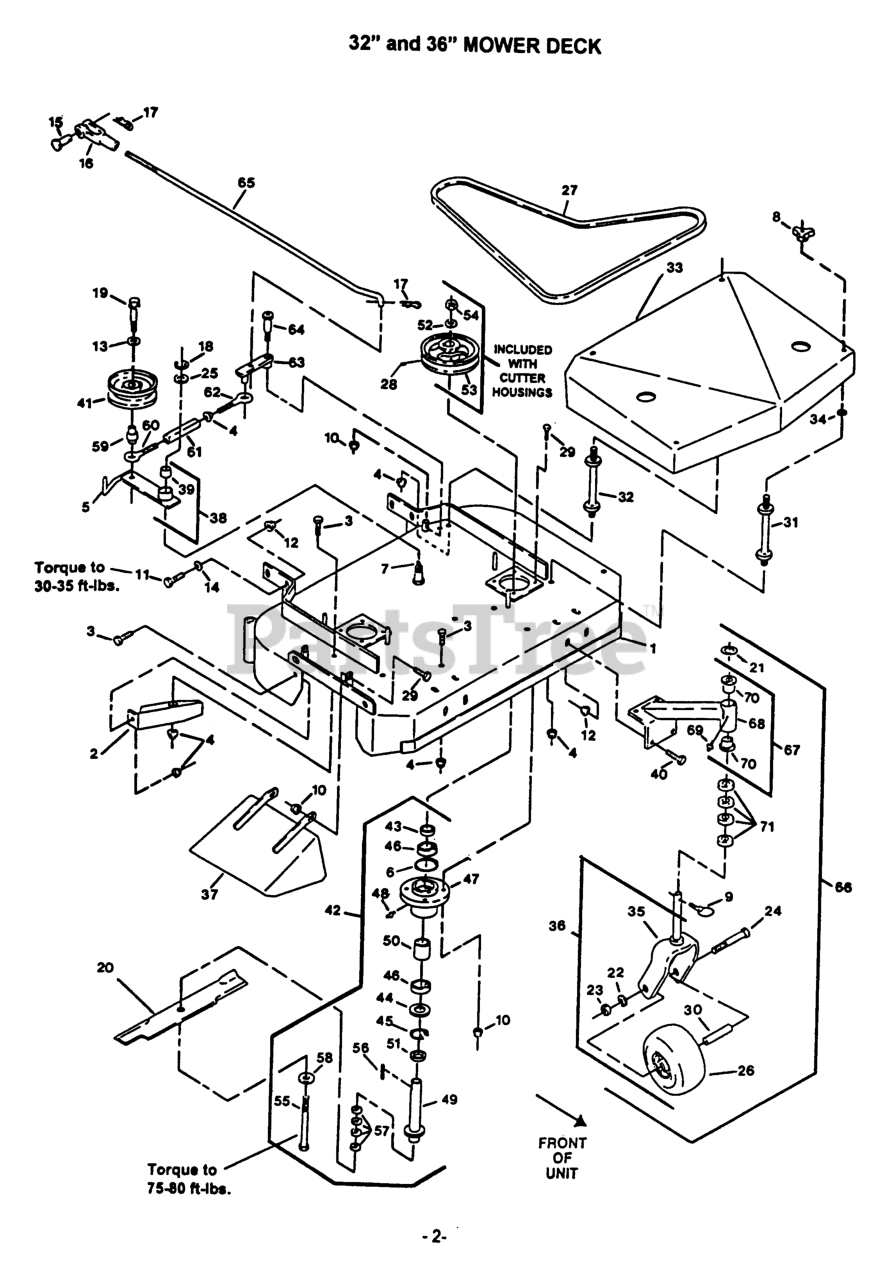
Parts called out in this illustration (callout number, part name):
2	BAFFLE-DOGLEG
8	KNOB-3 PRONG
15	PIN-CLEVIS
16	YOKE-ADJUSTABLE
17	PIN-COTTER
21	WASHER-FLAT
25	WASHER-SPINDLE
27	BELT,BLADE DRIVE
28	SCREW-SET
31	STUD-SHIELD, BELT (SHORT)
32	STUD-SHIELD, BELT (LONG)
37	Chute
39	BEARING,POWDERED METAL
42	ASM,HOUSING CUTTER
44	SEAL,DUST
45	RING,SNAP WLDS N5000-244
46	BEARING,HD SPINDLE
47	HOUSING,CUTTER
50	SPACER,BRG/BRG
51	SPACER,BEARING &SPINDLE
52	WASHER-RETAINER, SHEAVE
55	SCREW-CAP, HH
58	WASHER-SPRING
59	BUSHING-ENGAGEMENT
60	EYEBOLT-THREAD, LH
61	BODY-TURNBUCKLE
62	EYEBOLT-THREAD, RH
64	BOLT,SHLDR KSKH
65	ARM-ASSIST, LINKAGE
66	CASTER/MOUNT ASM
67	SUPPORT ASM
70	BEARING-FLANGED
71	SPACER-CASTER
